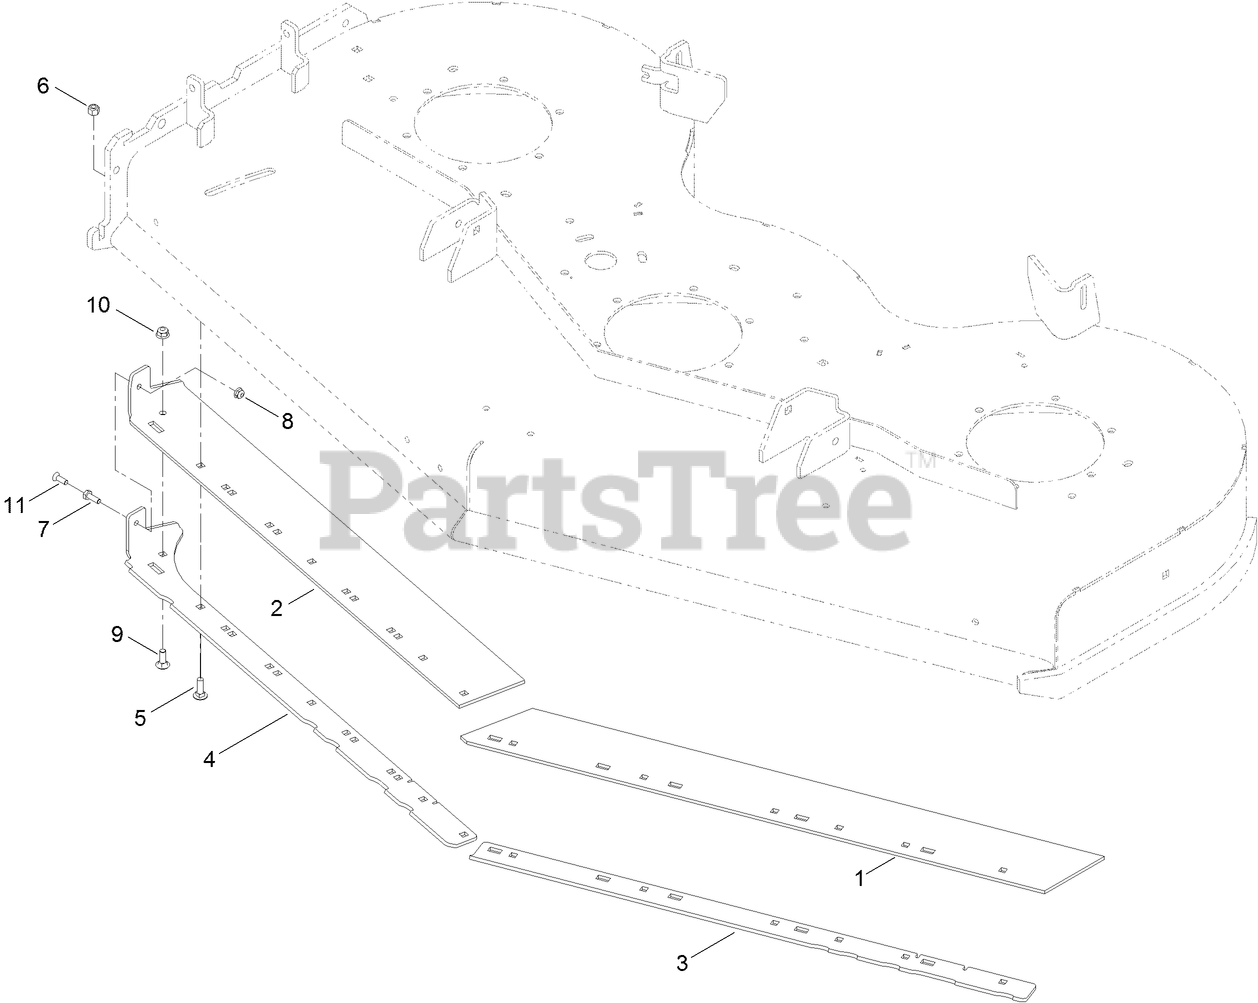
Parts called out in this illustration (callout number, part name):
1	RUBBER-LH
2	RUBBER-RH
5	BOLT-CARR
6	NUT-LOCK, NI
7	SCREW-HH
8	NUT-HF
9	SCREW-CARR
10	NUT-HF, NI
11	SCREW-FH
